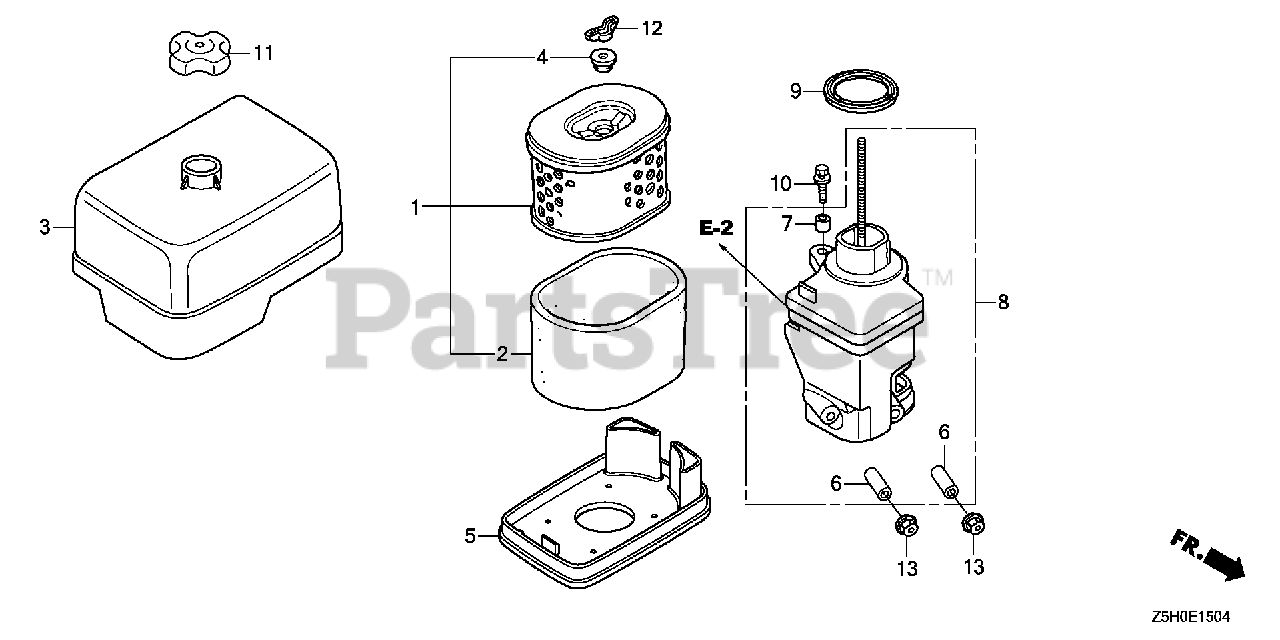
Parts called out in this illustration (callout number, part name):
1	ELEMENT, AIR CLEANER (DUAL)
2	FILTER (OUTER)
3	COVER, AIR CLEANER HOUSING
4	GROMMET, AIR CLEANER
5	NOSE, MUFFLER
6	COLLAR, AIR CLEANER
7	COLLAR B, AIR CLEANER
8	ELBOW, AIR CLEANER
9	GASKET, AIR CLEANER HOUSING
10	BOLT-WASHER (6X22)
11	NUT, AIR CLEANER COVER
12	WINGNUT, TOOL BOX SETTING
13	NUT, FLANGE (6MM)
